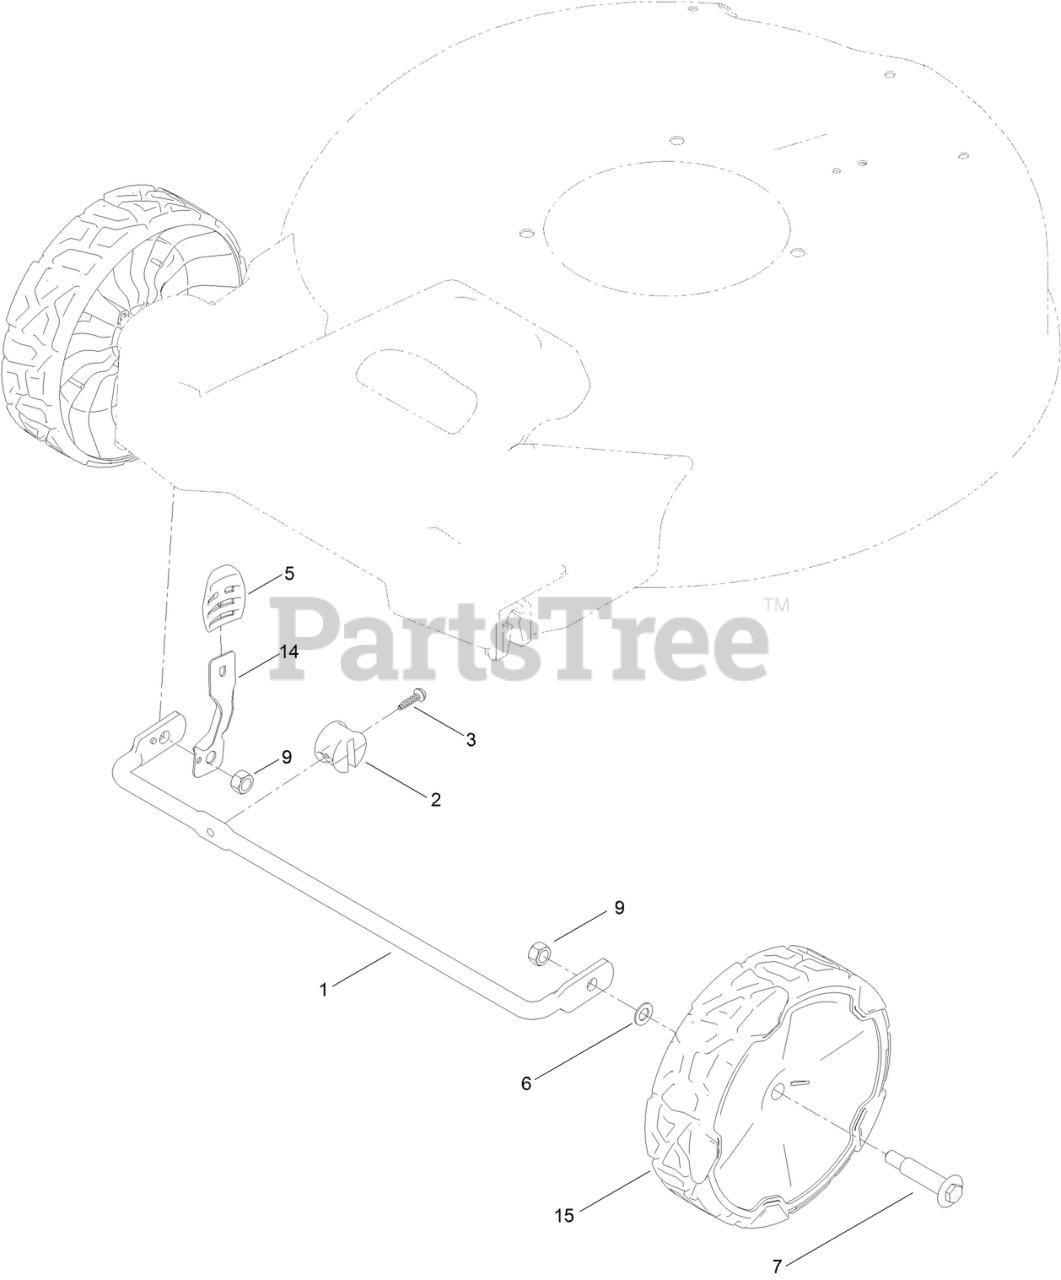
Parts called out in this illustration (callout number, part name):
1	AXLE-FRONT
2	STOP-AXLE
3	SCREW-HWH
5	KNOB-LEVER, HOC
6	WASHER-WHEEL BOLT
7	BOLT-SHOULDER
9	NUT-HEX
14	ARM-SPRING
15	ASM-8" WHEEL, IDLER
